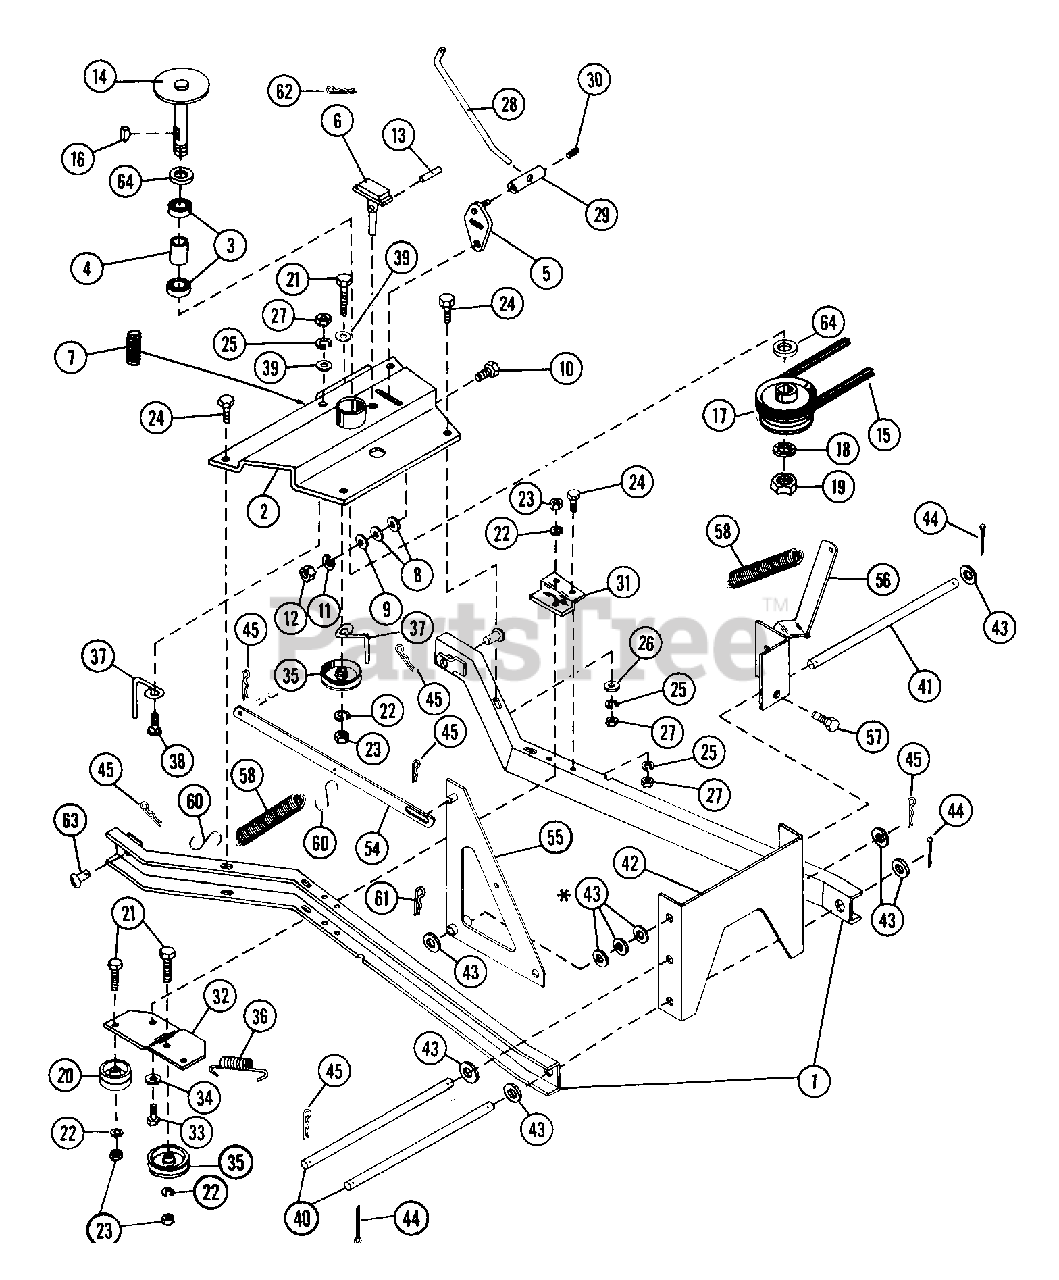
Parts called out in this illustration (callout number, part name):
1	CHANNEL
2	SPINDLE HOUSING
3	BRG-BALL .750X1.781X.61
4	SPACER .765X1.000X1.252
5	BRAKE ACTUATOR
6	BRAKE PLUNGER
7	SG-COMP ??X.44X?? WLD 10
8	WSHR-FL-STL .265X.500X.087 PL
9	WSHR-FL-STL.312X.734X.065PL
10	BLT-HEX .25-20X.75 PL GR5
11	WSHR-LK .250X.077 HVY PL
12	NUT-HEX .250-20 PL
13	PIN-ROLL .188X1.50
14	SPINDLE SHAFT
15	V-BELT, 4L-RAW EDGE
16	KEY-WDRF .188X.75X.313 SAE 9
17	DOUBLE SHEAVE
18	WSHR-LK-INT .750X.050 MED
19	NUT-JAM .75-10 PL
20	IDLER-FLAT 2.25 X .38
21	BLT-HEX .38-16X1.75 PL GR2
22	WSHR-LK .375X.115 HVY PL
23	NUT-HEX .375-16
24	BLT-HEX .31-18X.75 PL GR5
25	WSHR-LK .312X.097 PL HVY
26	WSHR-FL-STL .323X.625X.062 PL
27	NUT-HEX .312-18
28	BRAKE ROD
29	ROD ADAPTER
30	SCR-SET .32-18X.38 SKHCUPNL OH
31	IDLER MOUNT
32	IDLER ARM
33	SHOULDER BOLT .50 X .281
34	WSHR-FL-STL .511X1.441X.125 PL
35	IDLER-V 3.06 X .38
36	SG-TENS .080X.73X3.06 WLD 20
37	BELT FINGER
38	BLT-HEX .31-18X1.00 PL GR 2
39	WSHR-FL-STL .38X.875X.083 PL
40	PIVOT ROD
41	MOUNT ROD
42	PIVOT SUPPORT
43	WSHR-FL-STL.656X1.312X.095 PL
44	PIN-COTR .15X1.50
45	PIN-HAIR INT .09X.188 PL
53	CABLE RETAINER
54	LIFT STRAP
55	LIFT BELLCRANK
56	SPRING ANCHOR
57	BLT-HEX .50-13X1.25 PL GR2
58	SG-TENS .187X1.50X9.94 WLD 40
61	PIN-HAIR INT .14X.4X2.75
62	PIN-HAIR INT .08X.18X1.18
63	PIN-CLEV .494X1.25 YWZC
64	WSHR-FL-STL .781X1.250X.059 PL
